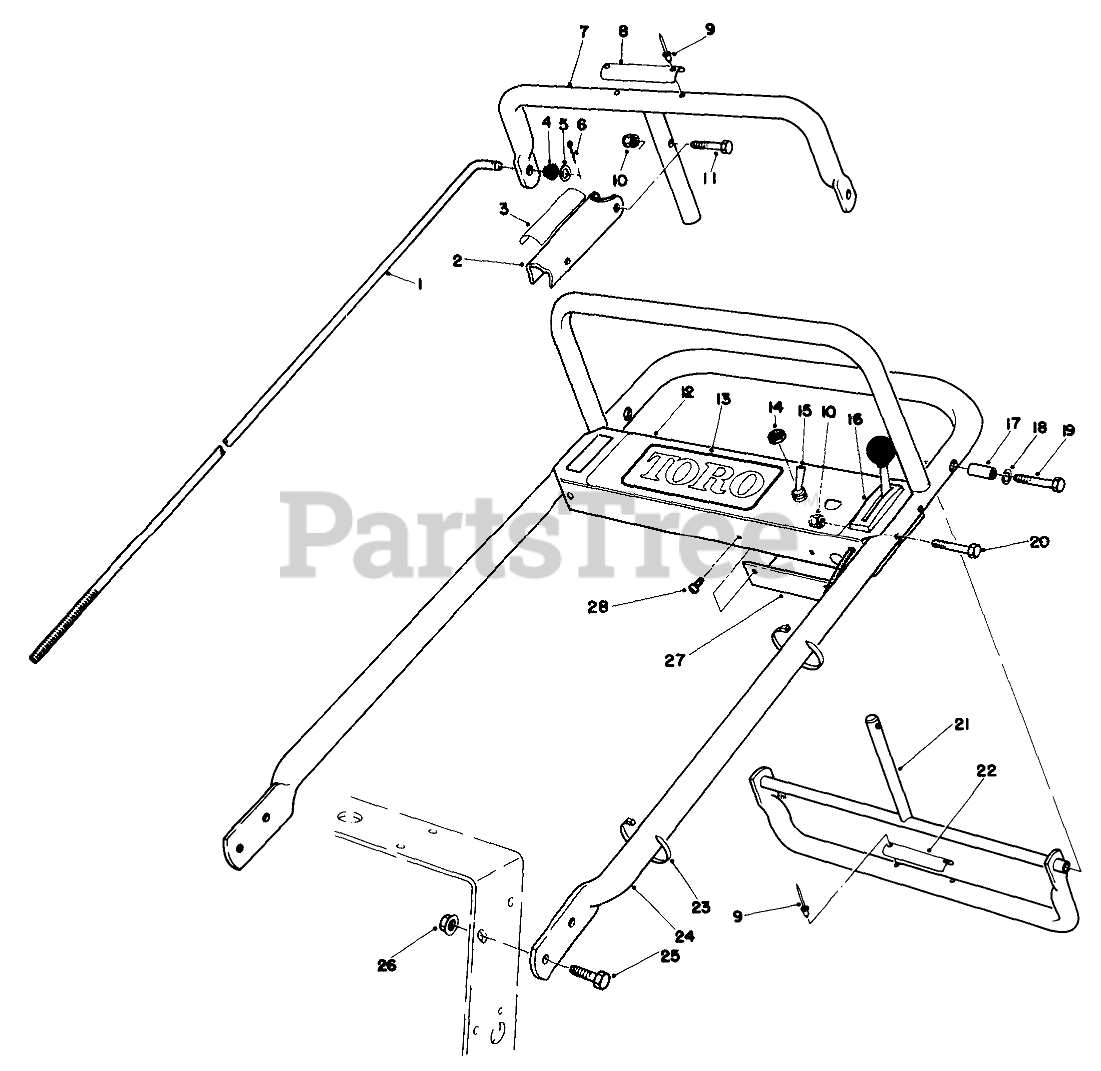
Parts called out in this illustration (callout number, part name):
1	ROD-CONTROL
2	Lever-Parking Brake
3	DECAL-LEVER, PARKING
4	GROMMET-RUBBER
5	WASHER-PLAIN
6	PIN-COTTER
7	Bar-Control
8	DECAL-CONTROL BAR
9	RIVET-BLIND
10	NUT-LOCK, NI
11	SCREW-SHH
12	Panel-Control
13	PANEL DECAL
14	NUT
15	Switch
16	THROTTLE-CONTROL
17	PIVOT-SPACER
18	WASHER-LOCK
19	SCREW-HH
20	SCREW-SHH
21	Control-Pivot
22	DECAL-REVERSE HANDLE
23	TIE-CABLE
24	HANDLE-UPPER
25	SCREW-HHF
26	NUT-HF
27	PANEL-BOTTOM
28	SCREW-HWHTF
